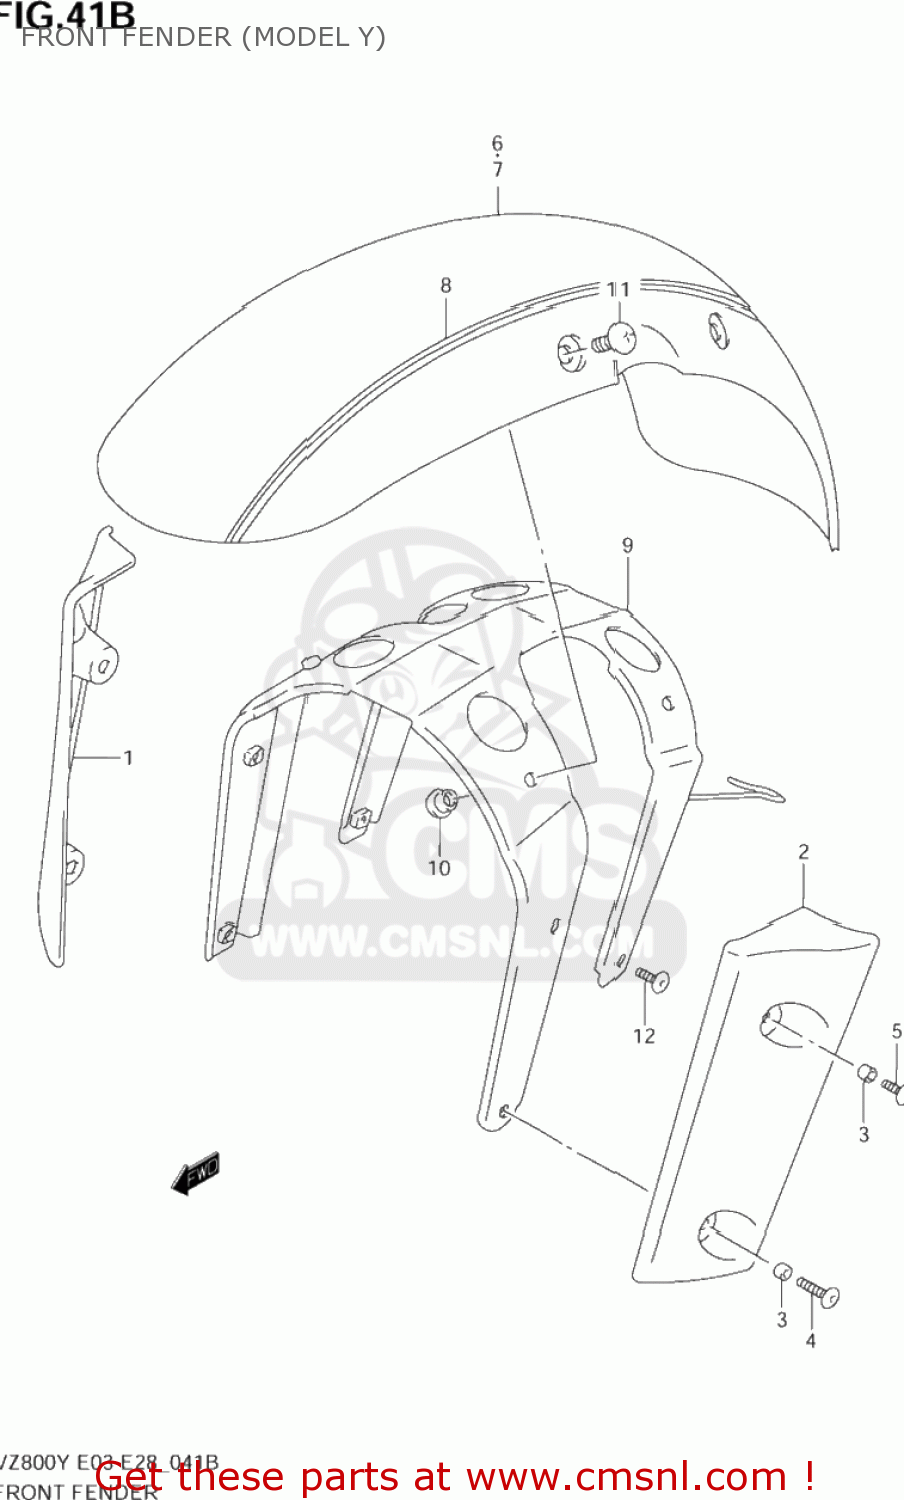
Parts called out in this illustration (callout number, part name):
1	COVER,FR FORK SIDE,R
2	COVER,FR FORK SIDE,L
3	SPACER(6.1X8X3.5)
4	SCREW(6X20)
5	SCREW(6X12)
6	FENDER,FRONT (BLACK)
7	FENDER,FR
8	TAPE SET,FR FENDER
9	BRACE,FR FENDER
10	NUT
11	SCREW(6X12)
12	SCREW(6X16)
